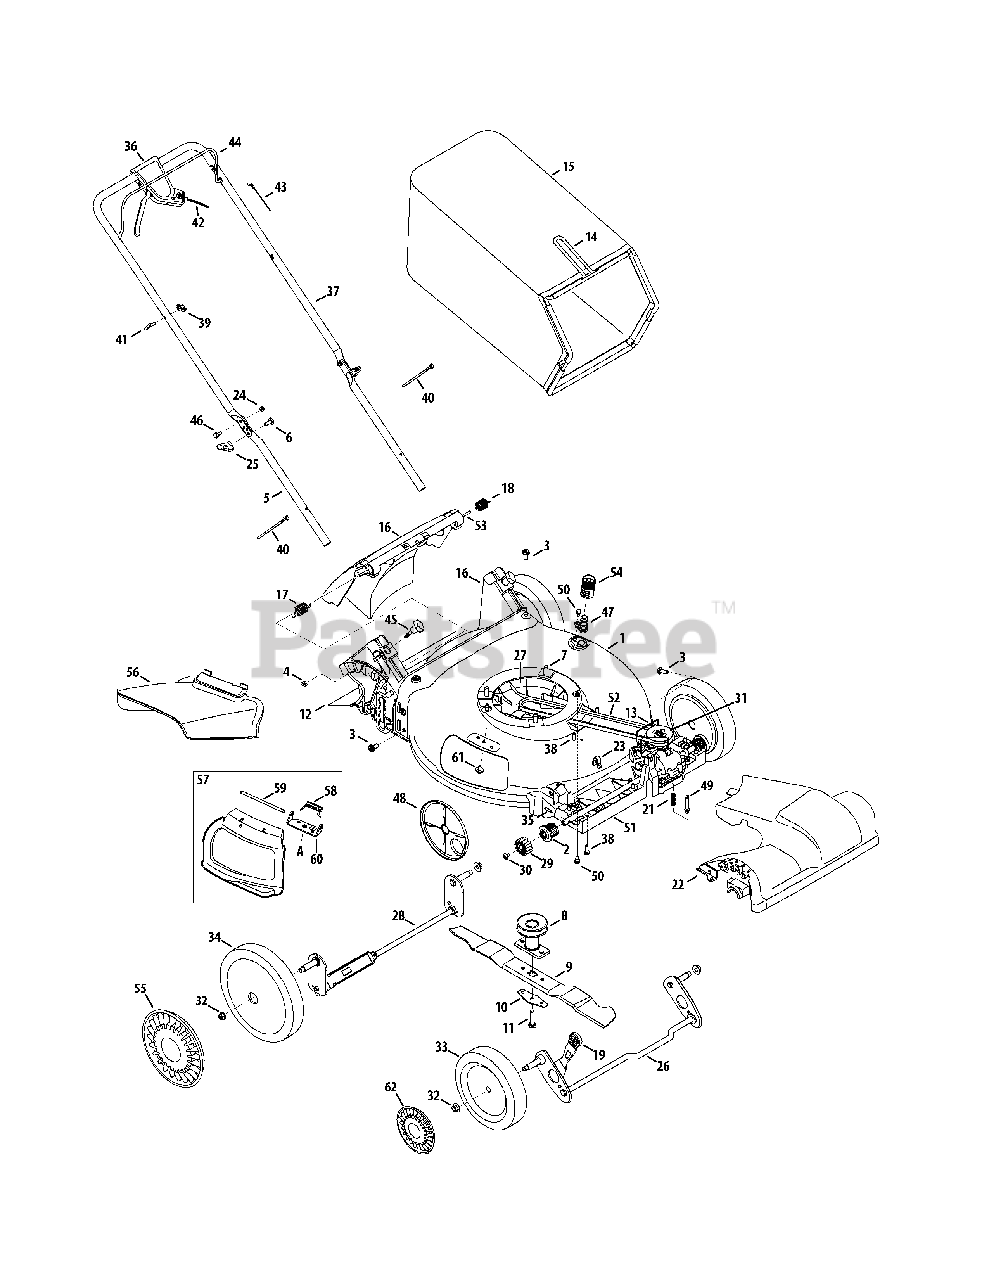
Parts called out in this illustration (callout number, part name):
1	21" Deck Ass’y (w/ side dis. w/nozzle)
2	Bearing Assembly
3	Hex Hd. Cap Scr. 5/16-14 x .75
4	Sq. Nut 1/4-20
5	Lower Handle
6	Carriage Bolt 5/16-18
7	Hex Wash HD Tap Scr 3/8-16 x 1.0
8	Blade Adapter
9	21" Mulching Blade
10	Blade Bell Support
11	Hex Bolt 3/8-24 x 1.5" Lg. (Gr 8)
12	Trailing Shield 4.54 x 17.37
13	Wire
14	Catcher Frame
15	Grassbag, Black Dust Blocking
16	Rear Baffle Ass’y (Incl. door)
17	RH Torsion Spring
18	LH Torsion Spring
21	Compression Spring 1.320
22	Front Axle Cover
23	Axle Clip
24	Flanged Lock Nut 1/4-20 Gr. F Nylon
25	Wing Knob
26	Front Axle Ass’y - 8 " wheel
27	Engine Baffle Ass’y
28	Rear Axle Ass’y - 8" wheel
29	Spur Gear 14 T LH
29	Spur Gear 14 T RH
30	Screw 1/4-20 x .390
31	Transmission Ass’y
32	Flange Locknut 3/8-16 Gr. F Nylon
33	Front Wheel
34	Rear Wheel
35	Dowel Pin 3/16 x 3/4
36	Control Lever Ass’y
38	Screw, 1/4-15 x .750
39	Knob 1/4-20
40	Cable Tie
41	Rope Guide Bolt
42	Drive Cable
43	Control Cable
44	Blade Control
45	Knob 1/4-20 x 1.73 Black
46	Shoulder Screw .375 x .126 x 1/4-20
47	Deck Water Nozzle
48	Dust Cover
49	Compression Spring Body
50	Shoulder Scr. 1/4-20 x .50
51	Front SP Tray
52	V Belt
53	Pivot Rod
54	Water Nozzle Adapter
55	Hub Cap (11")
56	Chute Deflector
57	Mulching Plug Ass’y (Incl. ref. no. 58-60)
58	Torsion Spring
59	Hinge Pin
60	Chute Deflector Bracket
61	Screw 1/4-20 x .50
62	Hub Cap
